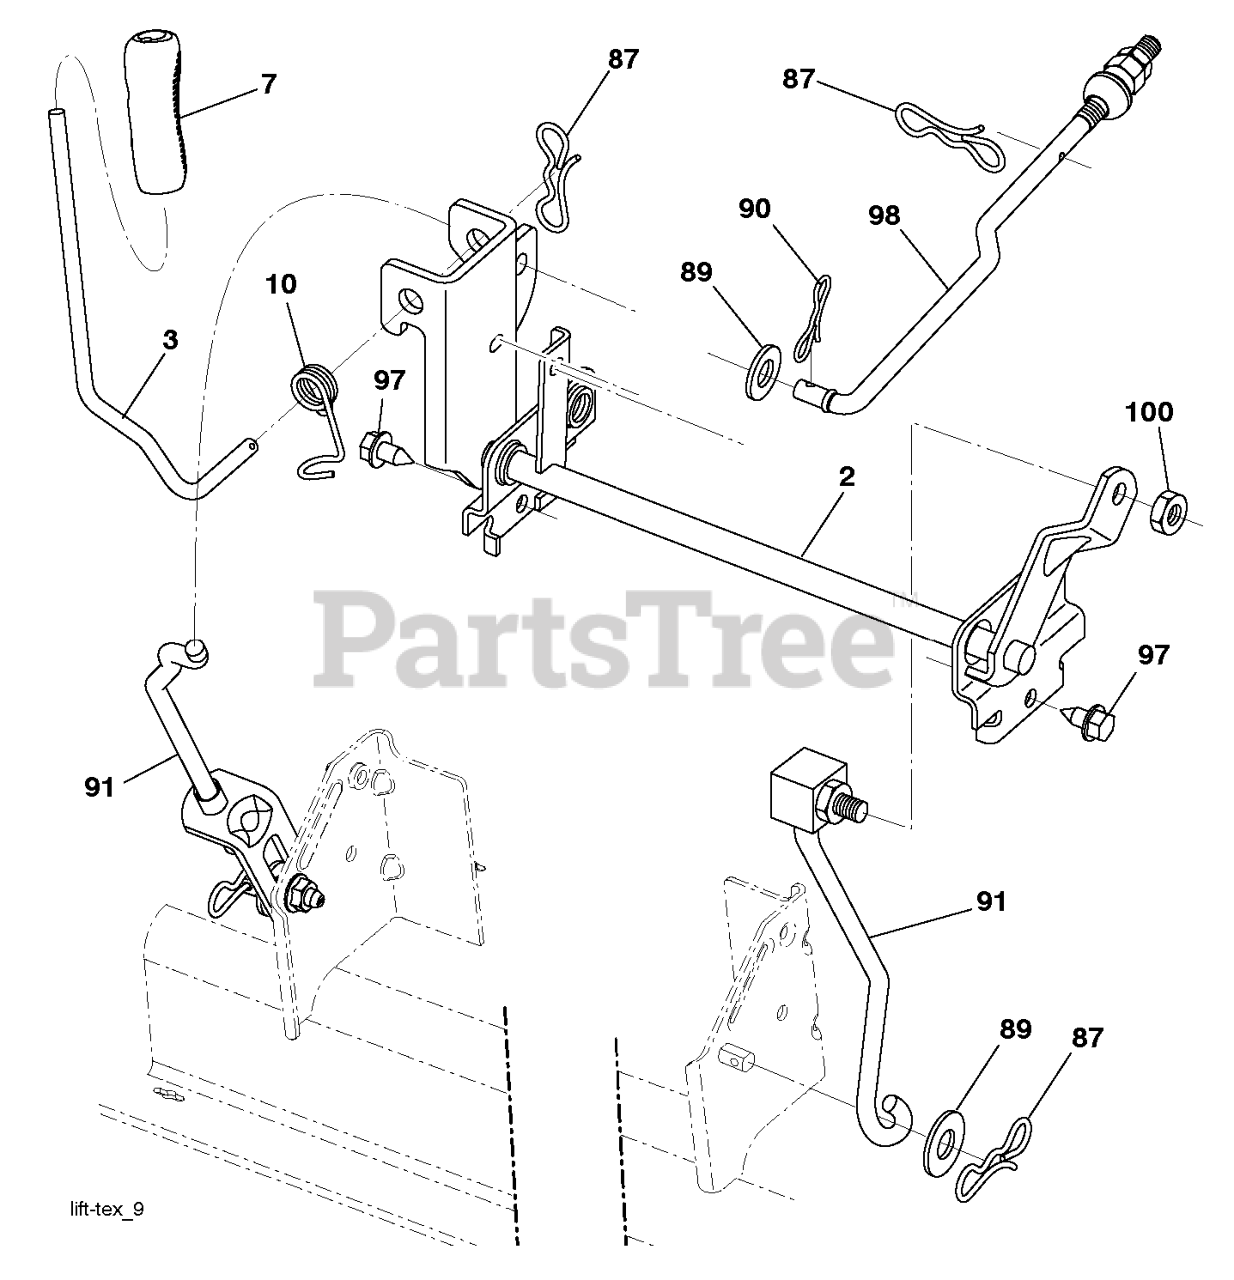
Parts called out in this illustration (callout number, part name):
2	SHAFT.ASM.LIFT.CROSS.H
3	LEVER.LIFT.HANDLE.LT
7	GRIP.LEVER.5625.ID
10	SPRING.TORSION.LIFT.HANDLE
87	PIN.COTTER.7/16.BOW TI.
89	WASHER.CLEAR.ZINC
90	PIN.COTTER.5/16.BOW TI
91	LIFT LINK SUSP. MOWER REAR
97	SCREW 3/8-16X3/4
98	LINK.ASM.SUSP.FRONT.MW
100	LOCKNUT
